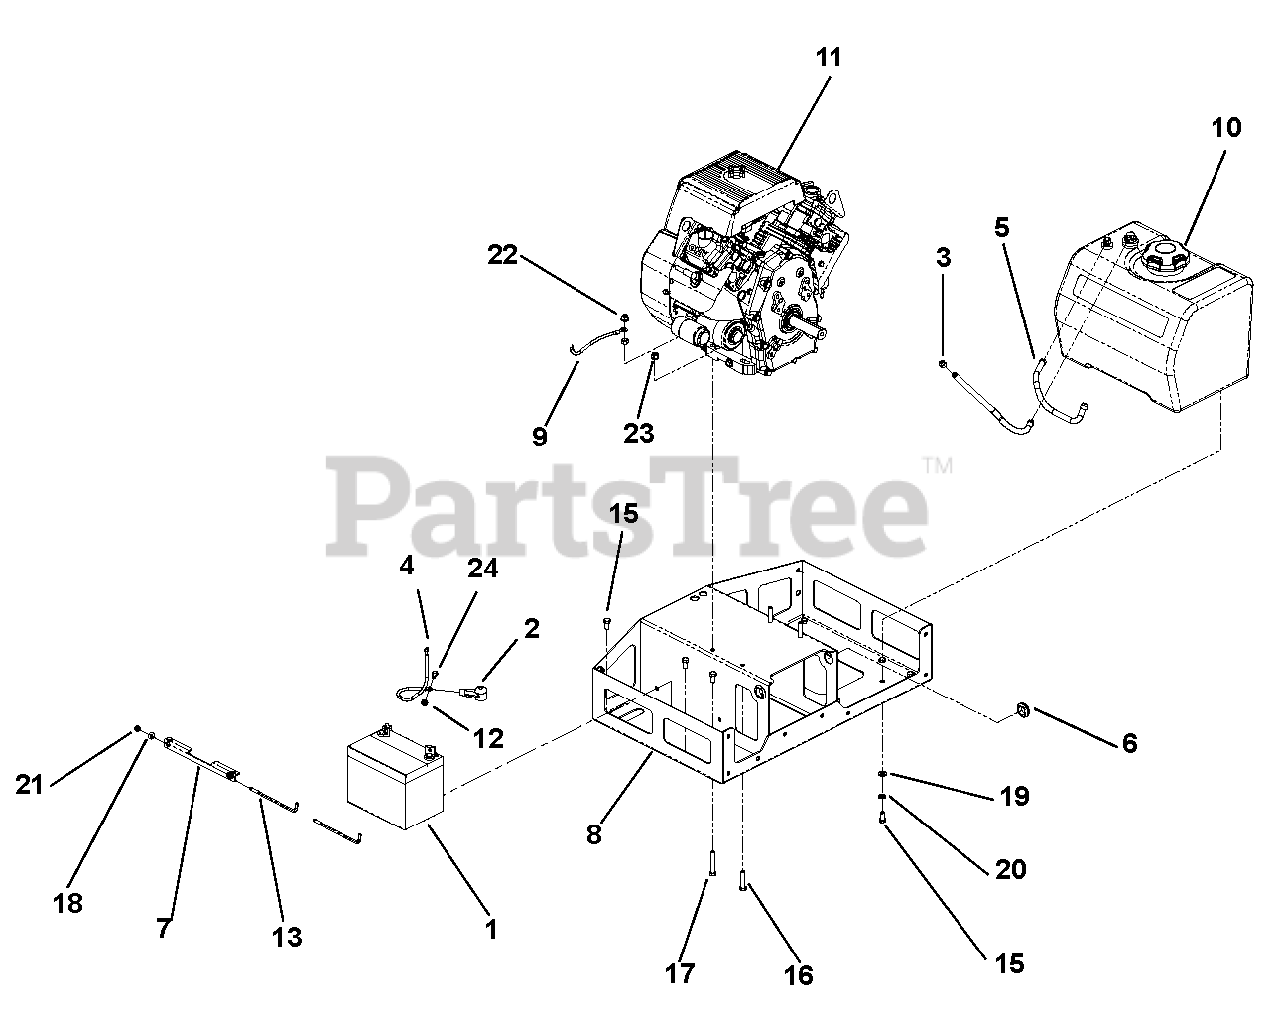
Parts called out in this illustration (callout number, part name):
1	Battery, 12V-U1-CCA270MIN
2	Battery Terminal Boot, Red
3	Clamp, Fuel Line
4	Cable, Positive Battery 9.00" REVA2
5	Gas Hose, Low Perm .25 x 18"
6	Grommet, Rubber .88 ID x 1.38 OD x .14 GR
7	Strap, Battery Hold Down
8	Weldment, Frame Base
9	Cable, Battery Negative 10" .25 x .37
10	Fuel Tank Assembly
11	Engine, Subaru 22 HP (995841)
12	Nut, Lock Flange .25-20 YWZC
13	J-Bolt, 1/4-20
14	Ring, Rubber Foot
15	Bolt, Hex .38-16 x .75 Grade 5 YWZC
16	Bolt, Hex .38-16 x 1.75 Grade 5 YWZC
17	Bolt, Hex .38-16 x 2.25 Grade 5 YWZC
18	Washer, Flat .281 x .62 x .065 Stl YWZC
19	Washer, Flat 1.010 x 1.505 x .062 Stl YWZC
20	Washer, Lock .38 x .094 Reg YWZC
21	Nut, Nyloc .25-20 YWZC
22	Nut, Nyloc Flange .38-16 YWZC
23	Nut, Hex .38-16 YWZC
24	Screw, Flange Head 1/4-20 x 5/8
